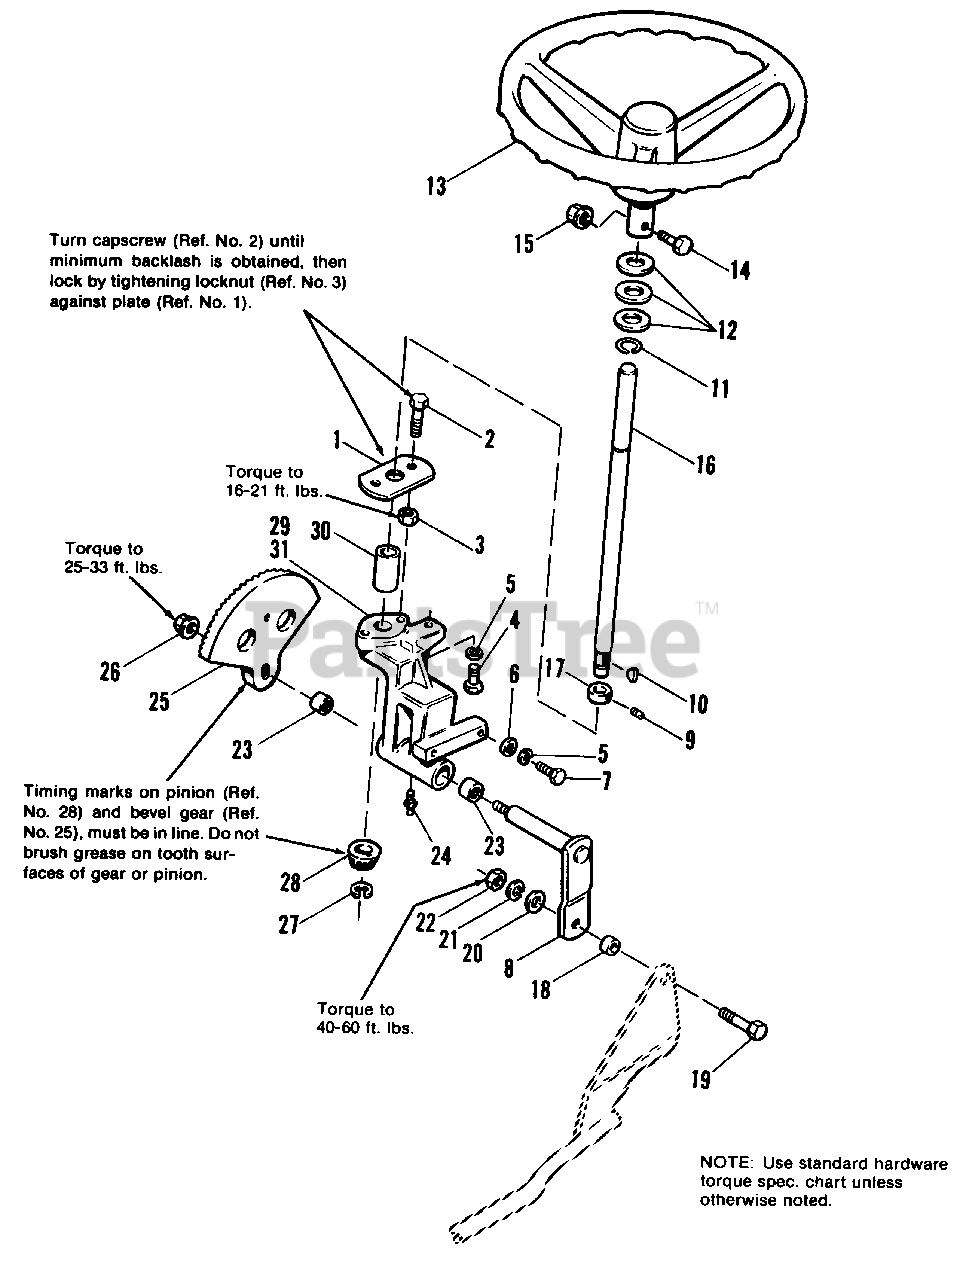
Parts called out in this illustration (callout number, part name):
1	PLATE, Steering
2	CAPSCREW, Hex Hd., 3/8-16 x 1-1/4
3	LOCKNUT, Hex, Jam, 3/8-16
4	CAPSCREW, Hex, 3/8-16 x 3/4
5	LOCKWASHER, 3/8
6	WASHER, Plain, 3/8
7	CAPSCREW, Hex Hd., 3/8-16 x 7/8
8	ARM ASSY., Steering
9	SETSCREW, Skt. Hd., 5/16-18 x 1/4
10	KEY, Woodruff #6, 5/32 x 5/8
11	RING, Retaining
13	WHEEL, Steering
14	CAPSCREW. Hex Hd., 5/16-18 x 1-1/4
15	LOCKNUT, Flange, 5/16-18
16	SHAFT, Steering
17	COLLAR, Set
19	CAPSCREW, Hex Hd., 1/2-13 x 1-1/2
20	WASHER, Plain
21	LOCKWASHER, 1/2
22	NUT, Hex, 1/2-13
23	BEARING, Needle
24	FITTING, Grease
25	GEAR, Bevel
26	LOCKNUT, Hex, Flange, 7/16-14
27	"E" RING
28	PINION, Bevel
29	HOUSING ASSY., Steering
